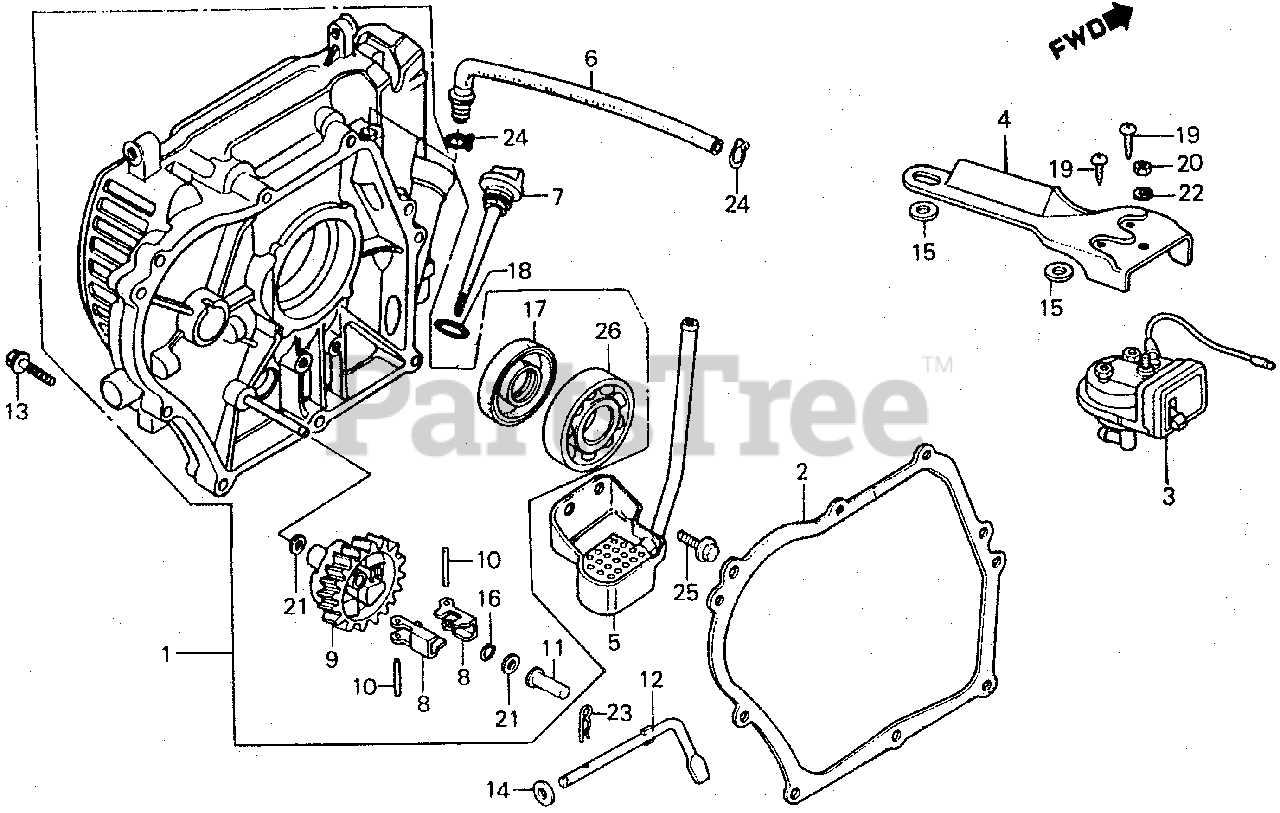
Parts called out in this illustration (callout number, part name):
1	COVER ASSY., CRANKCASE
2	GASKET, COVER
3	SWITCH ASSY.
4	BRACKET, UNIT SWITCH
6	TUBE, OIL ALERT
7	CAP, OIL FILLER
8	WEIGHT, GOVERNOR
9	HOLDER, GOVERNOR WEIGHT
10	PIN, GOVERNOR WEIGHT
11	SLIDER, GOVERNOR
12	SHAFT, GOVERNOR ARM
13	BOLT, FLANGE (6X32)
14	WASHER, THRUST (6MM)
15	WASHER (18MM)
16	CLIP, GOVERNOR HOLDER
17	OIL SEAL (25X41.25X6)
18	O-RING (16MM)
19	SCREW, TAPPING (5X10)
20	NUT, HEX. (5MM)
21	WASHER, PLAIN (6MM)
22	WASHER, SPRING (5MM)
23	PIN, LOCK (10MM)
24	CLIP, TUBE (C11)
25	BOLT, FLANGE (6X12)
26	BEARING, RADIAL BALL (6205)
